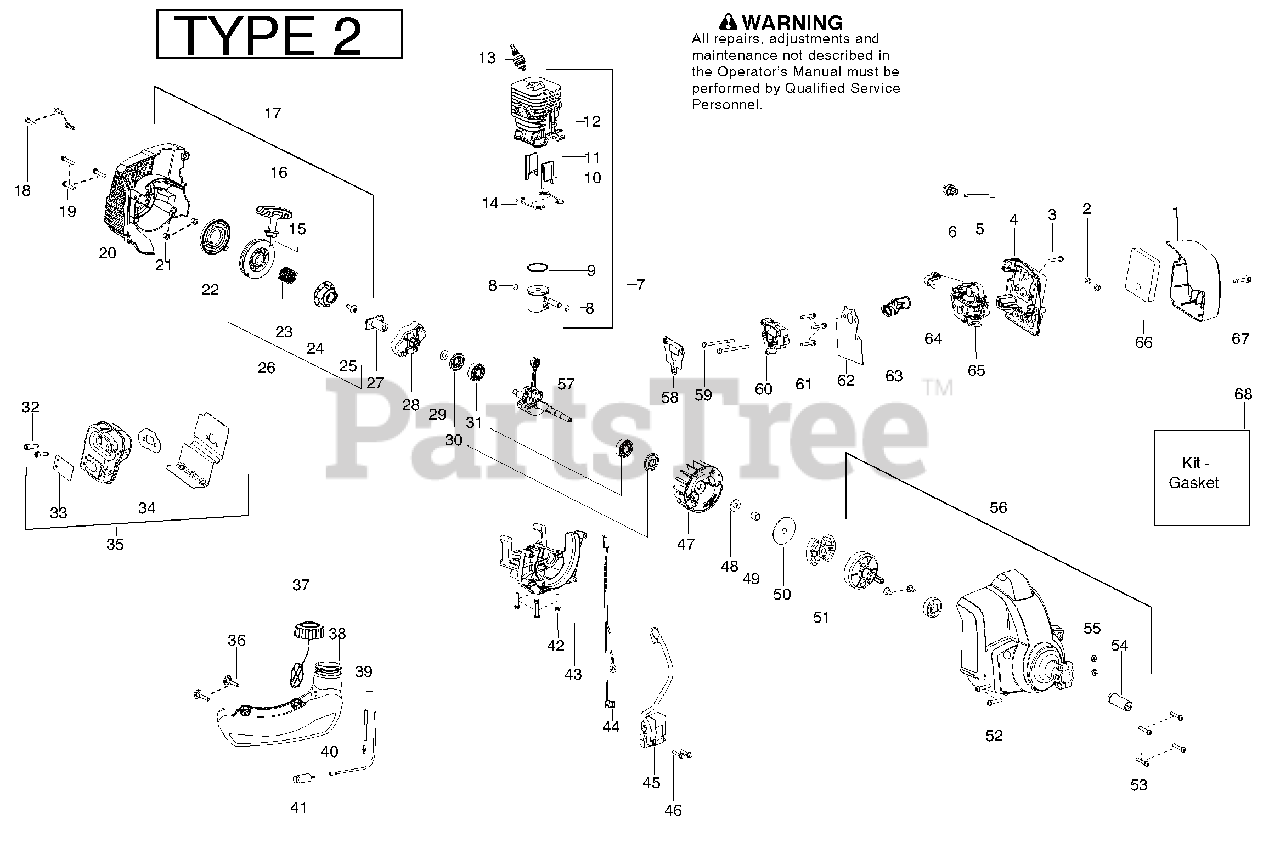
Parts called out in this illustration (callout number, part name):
1	Cover - Airbox
2	Nut - Carb. Screw
3	Screw 8-32
4	Base - Airbox
6	Assy - Purge Bulb
7	Kit - Piston/Cylinder
8	Retainer - Piston pin
9	Ring - Piston
10	Insert - Front Transfer Port
11	Insert - Rear Transfer Port
12	Cylinder - Machined
13	Spark Plug (RCJ- 6Y)
14	Seal - Cylinder (Kit)
15	Kit - Rope
16	Handle - Starter
17	Assy - Starter/Shroud
18	Screw M4 x 1.75
19	Screw M5x25mm
20	Assy - Starter Hsg. w/eyelet
22	Kit - Starter Spring
23	Spring - Starter Hub
24	Hub - Starter
25	Screw M6
26	Kit - Starter Pulley
27	Coupling - Starter
28	Assy - Starter Cup
29	Washer - Flat
30	Seal - Crankshaft (kit)
31	Bearing - Crankshaft
32	Bolt - Muffler
33	Kit - Spark Arrestor
34	Gasket - Muffler (kit)
35	Assy - Muffler
36	Screw - Tank Retainer
37	Assy - Fuel Cap w/ret.
38	Assy - Tank
39	Kit - Fuel line
40	Fitting - Fuel Line
41	Assy - Fuel Pickup
42	Screw - M5x25mm
43	Crankcase
44	Assy - Leadwire
45	Module - Ignition
46	Screw 8-32
47	Flywheel
49	Spacer - Flywheel
50	Washer - Clutch
51	Kit - Clutch Assy.
52	Screw 10-24 x 1"
53	Screw M5 x 25mm
54	Guide - Clutch Drum
55	Locknut 10-24
56	Assy - Fan Housing
57	Kit - Crankshaft Assy.
58	Gasket - Adapter/Cyl. (kit)
59	Bolt M5 x .80
60	Adaptor - Carburetor
61	Screw .20 x 32
62	Gasket - Carb./Adapter(kit)
63	Boot - Carb.
64	Lever - Choke
65	Carburetor (WTA-32)
66	Filter - Air
67	Bolt - Knob
68	Kit - Gasket
